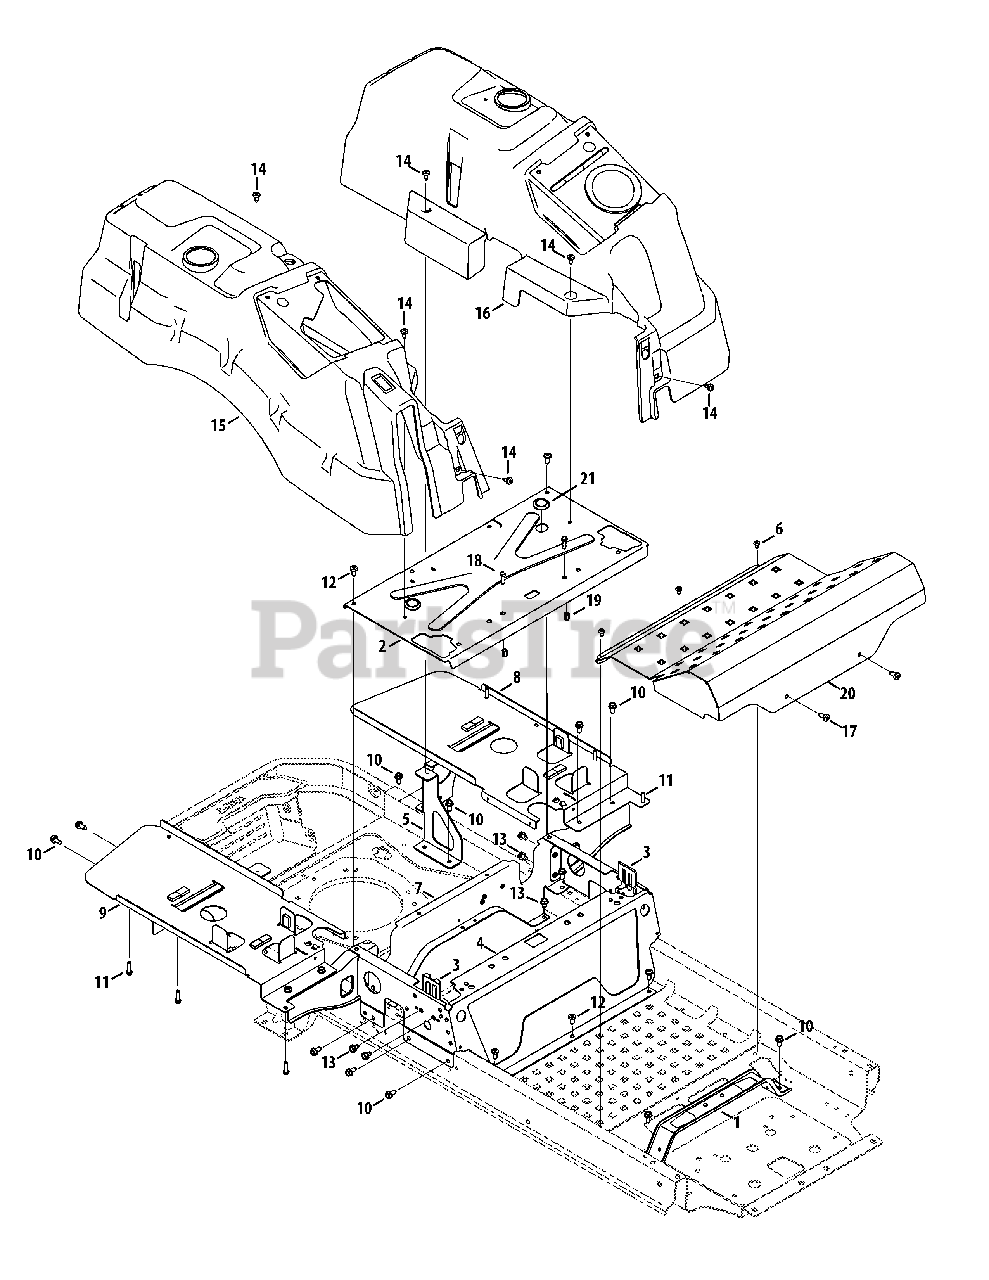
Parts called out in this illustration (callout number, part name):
1	Steering Support Bracket
2	Seatbox Plate
3	Lapbar Brace Bracket
4	Seat Frame
5	Rear Support Bracket, LH
5	Rear Support Bracket, RH
6	Screw, 1/4-20 x .50
7	Rear Seatbox Brace
8	Tank Support Plate, LH
9	Tank Support Plate, RH
10	Hex Washer Screw, 5/16-18 x .750
11	Hex Washer Screw, 5/16-14 x 1.00
12	Self Tapping Screw, 5/16-18 x .750
13	Hex Washer Screw, 5/16-18 x .50
14	Shoulder Screw, 1/4-20
15	RH Console
16	LH Console
17	Screw, 5/16-18 x .75
18	Hex Cap Screw, 5/16-18 x 1.00
19	Nut, 5/16-18
20	Floor Board, Fab
21	Button Plug
